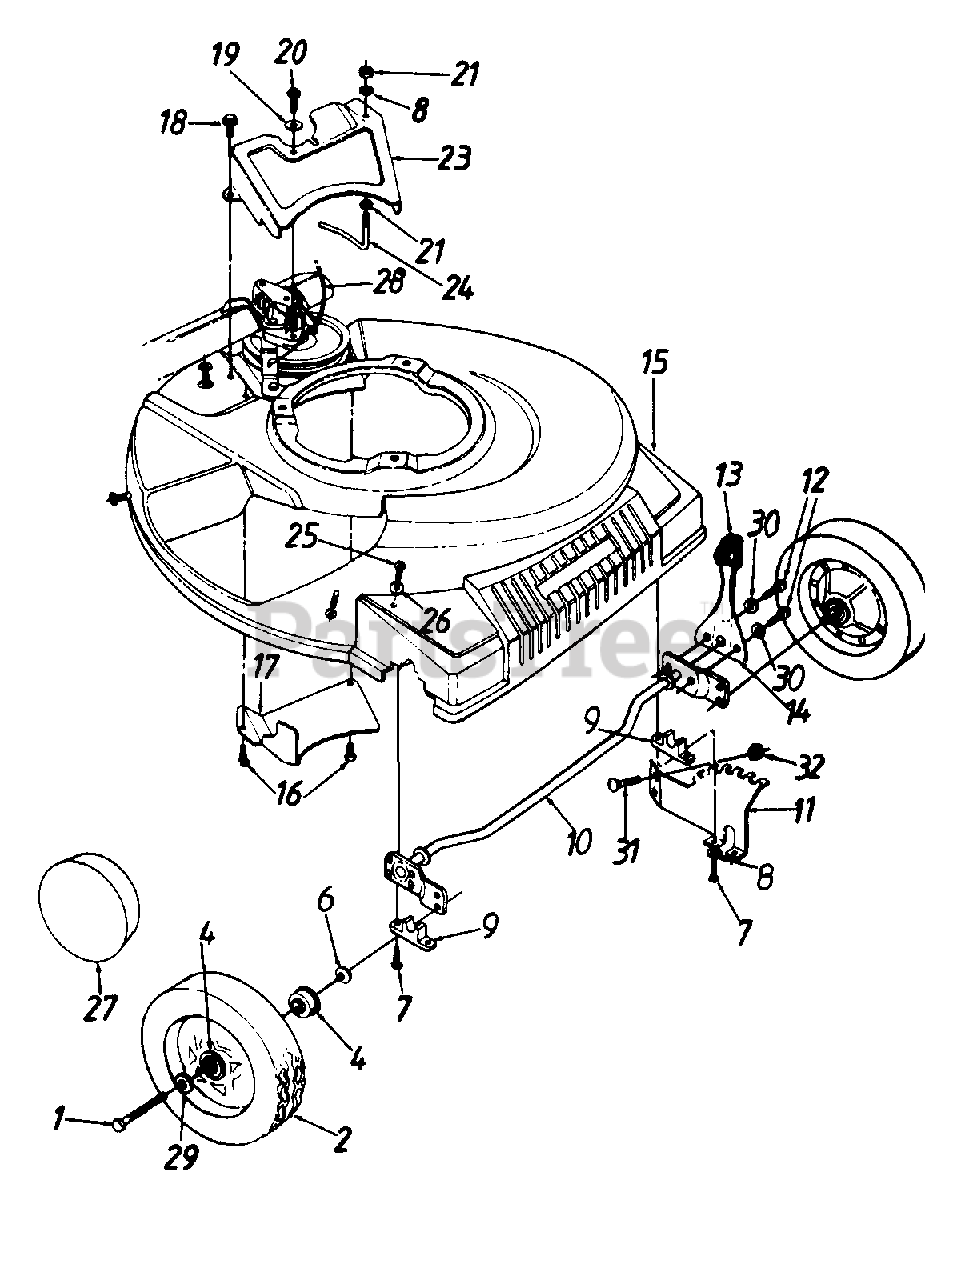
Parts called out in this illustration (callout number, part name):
1	Front Axle Bolt
2	Wheel Ass'y. Comp.
4	Flange Ball Brg. .501" I.D.
6	Bell-Wash. .380" I.D. x .88
7	Hex Wash. Hd. Scr. 1/4-20 x 1" Lg.
8	L-Wash. 1/4" I.D.
9	Block Bushing
12	Hex Wash. Hd. TT-Tap Scr. 1/4-20 x .38" Lg.
13	Knob
14	Spring Lever
15	Plastic Front End
16	Hex B-Tap Scr. 1/4" x .38"
19	Bell-Wash. .265" I.D. x .75"
20	Hex Wash. Hd. B-Tap Scr. 1/4 x .62" (Spec.)
21	Hex Nut 1/4-20 Thd.
25	Torx Truss Hd. Scr. 5/16 x .75"
26	Bell-Wash. .345" I.D. x .88" O.D.
27	Hub Cap
28	S.P. Cable 50" Lg.
29	Wave Wash. .51" I.D. x .75" O D.
30	External L-Wash. 1/4" I.D.
31	Carr. Bolt 1/4-20 x .5" Lg.
32	Hex L-Nut 1/4-20 Thd.
